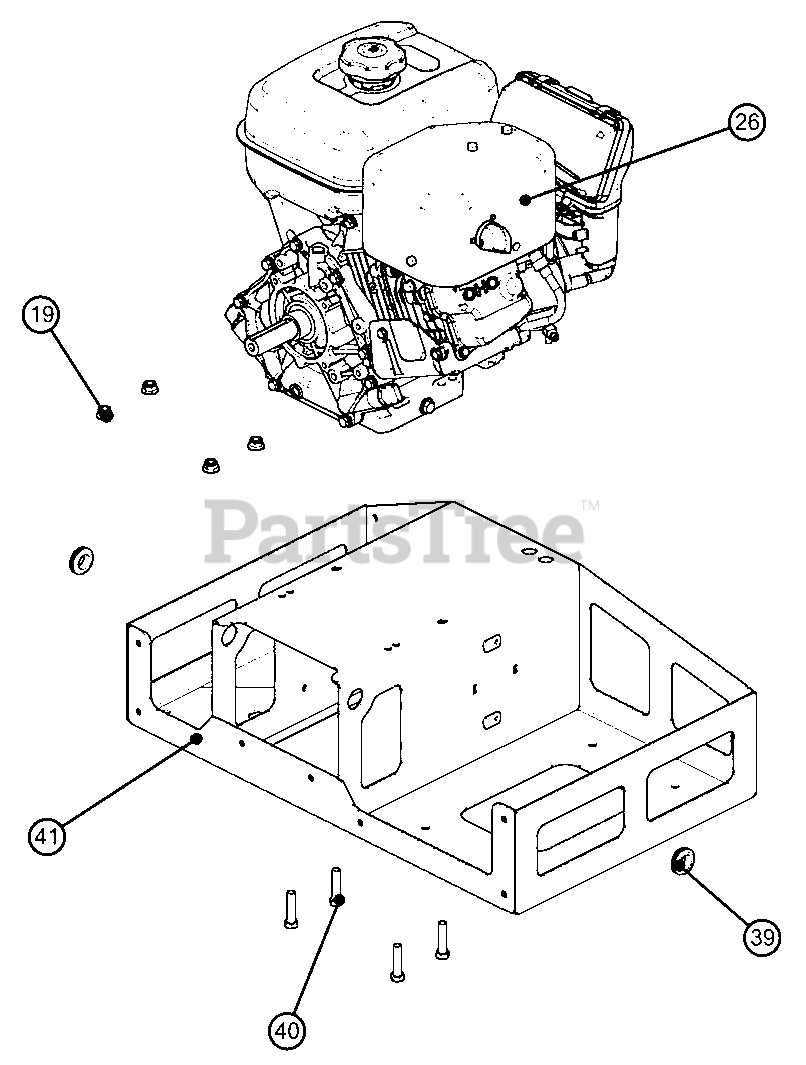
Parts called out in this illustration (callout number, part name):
19	NUT-LK-NYL-FLG .38-16 YWZC
26	14HP ROBIN EX40 ENGINE
39	GROMMET: RUB: .88id x 1.38ODX .14GR
40	BLT-HEX .38-16 X 1.75 GR5 YWZC
41	WLDT, FRAME BASE
